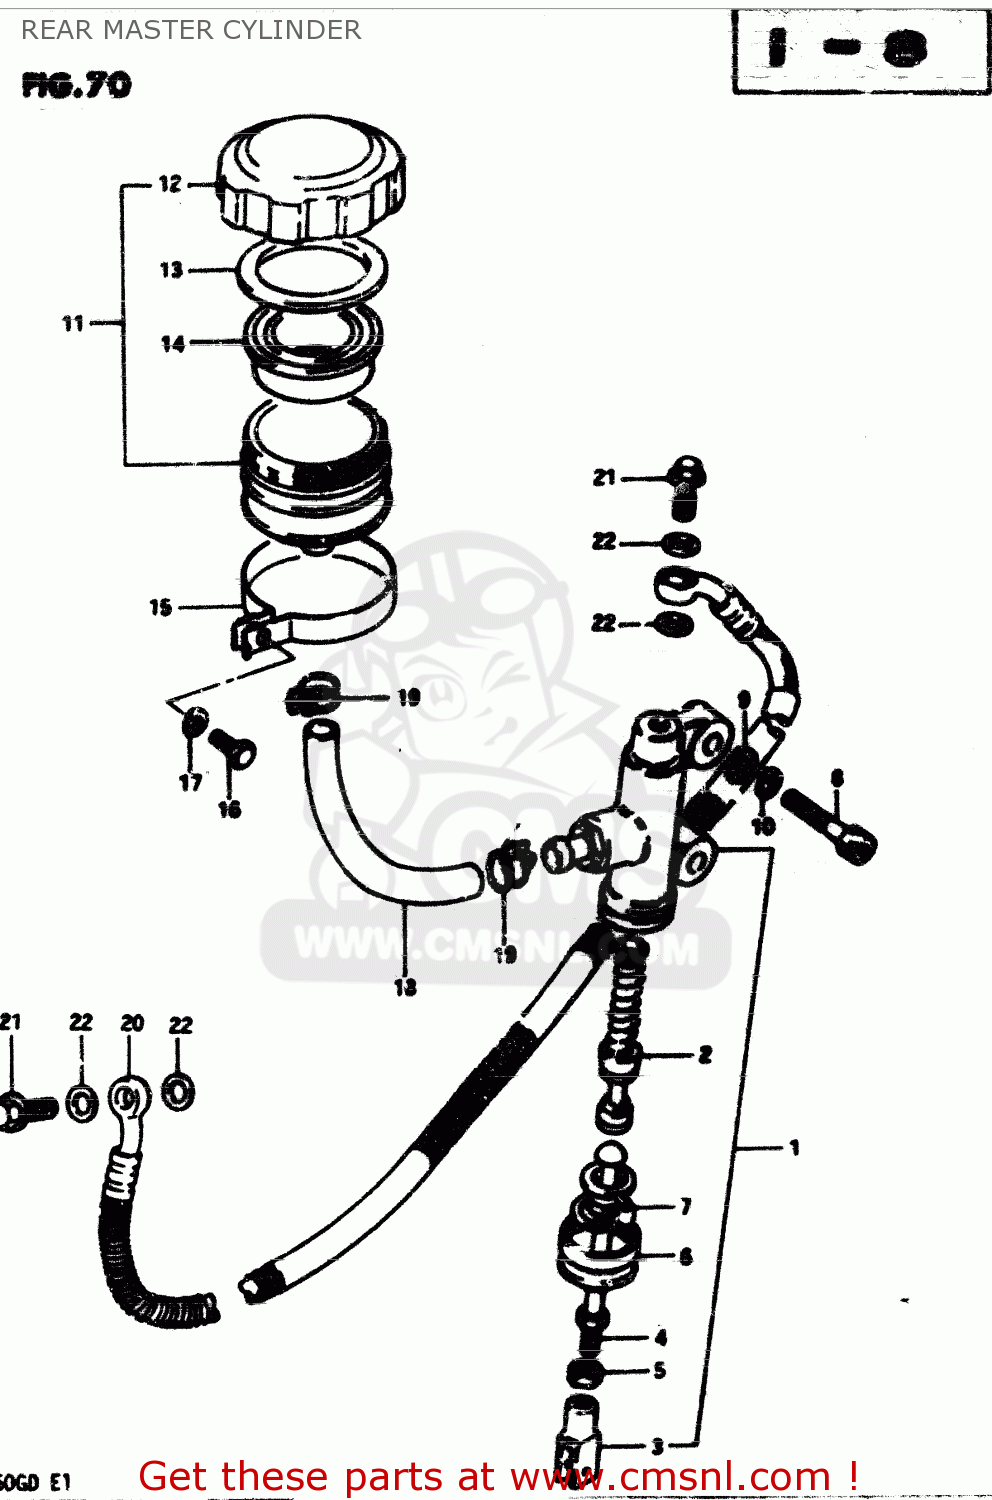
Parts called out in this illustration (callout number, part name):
1	CYLINDER ASSY, REAR MASTER
2	PISTON/CUP SET
3	YOKE
4	ROD,REAR MASTER CYLINDER
5	NUT,MASTER CYLINDER
6	BOOT
7	CIRCLIP
8	BOLT
9	WASHER
10	WASHER,LOCK,8.
11	TANK ASSEMBLY,RESERVOIR
12	CAP
13	PLATE,DIAPHRAGM
14	DIAPHRAGM
15	CLAMP
16	BOLT, UPPER
17	LOCK WASHER
18	HOSE,RESERVOIR TANK
19	CLAMP
20	HOSE,REAR BRAKE
21	BOLT,UNION
22	WASHER
